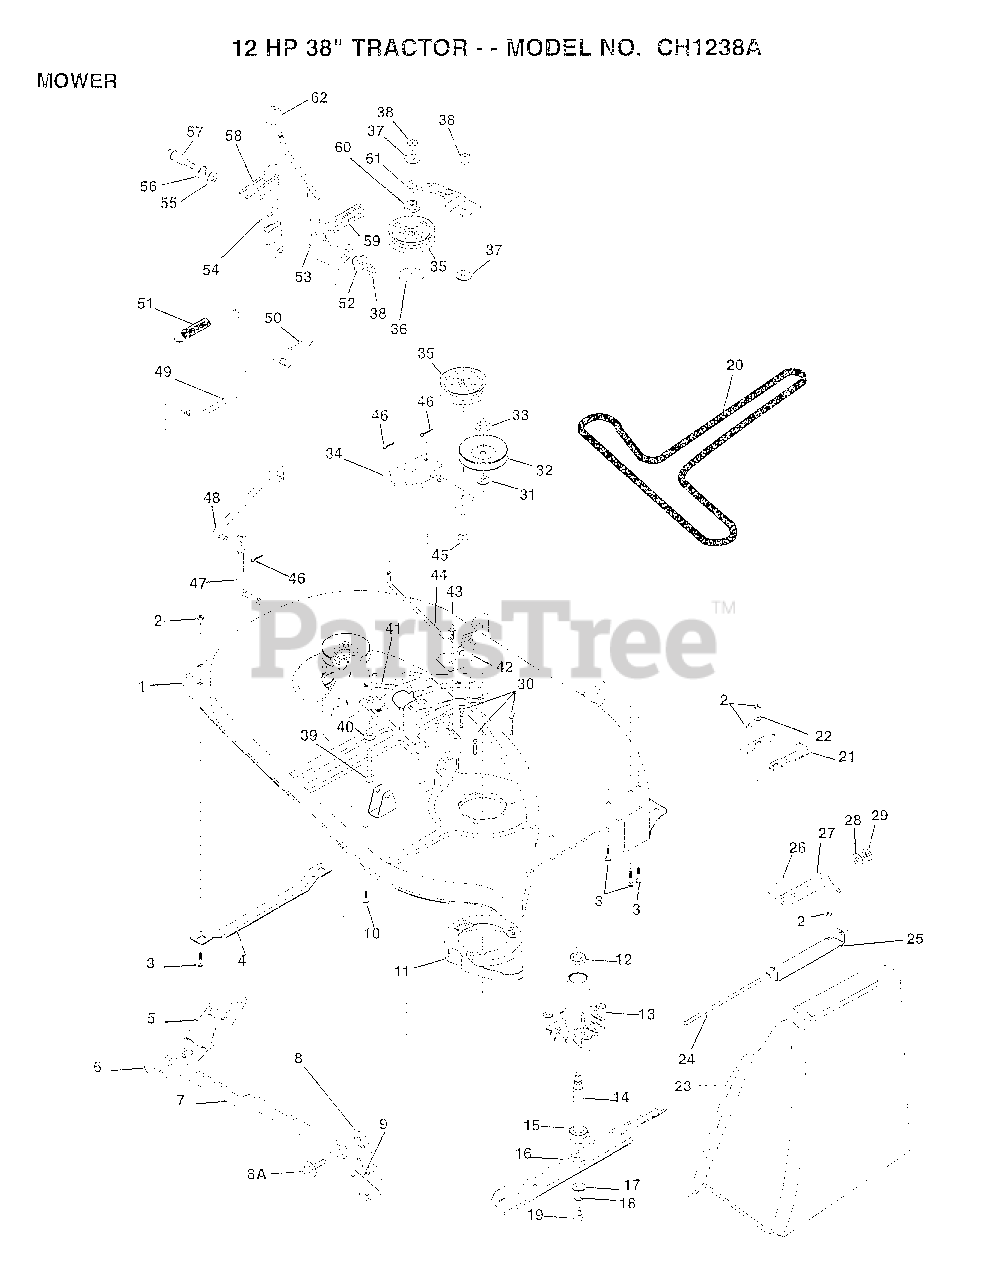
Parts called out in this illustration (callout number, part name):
3	BOLT
4	RUNNER-LH M
5	BRKT ASM SWAY BAR
8	BRKT DECK SW BAR
8A	BOLT SHD 5/16-18
9	NUT
10	BOLT
12	BEARING
13	HSG ASM MANDREL
15	BEARING.BALL
17	WASHER BLADE
19	BLADE BOLT
20	BELT-V.88.12.MW
21	RUNNER RH
22	WASHER M
23	DEFLECTOR-SHLD T
24	ROD-HINGE T
25	BRKT DEFLECTOR
26	CAP-SLEEVE LT
27	SPRING TORSION
28	WASHER
29	NUT PUSH M
31	WASHER
34	IDLER ARM ASSY
35	FLAT IDLER PULLEY
36	SPACER RETAINER
37	WASHER GT
39	BOLT
40	WASHER GT
41	BRAKE ROD LH
42	BRAKE ASM
43	SCREW
44	BRAKE ROD RH
45	BOLT
47	PIVOT ROD
48	CLUTCH ROD SECOND
49	"ROD, CLUTCH PRIM"
50	RETAINER M
51	RETURN SPRING
52	BUSHING
53	CLUTCH ARM PRI AS
54	CLUTCH ARM SECOND
55	WASHER
56	RING
57	SHOULDER BOLT
58	SPRING KEEPER
60	RETAINER SPACER
61	IDLER ARM STIFF
